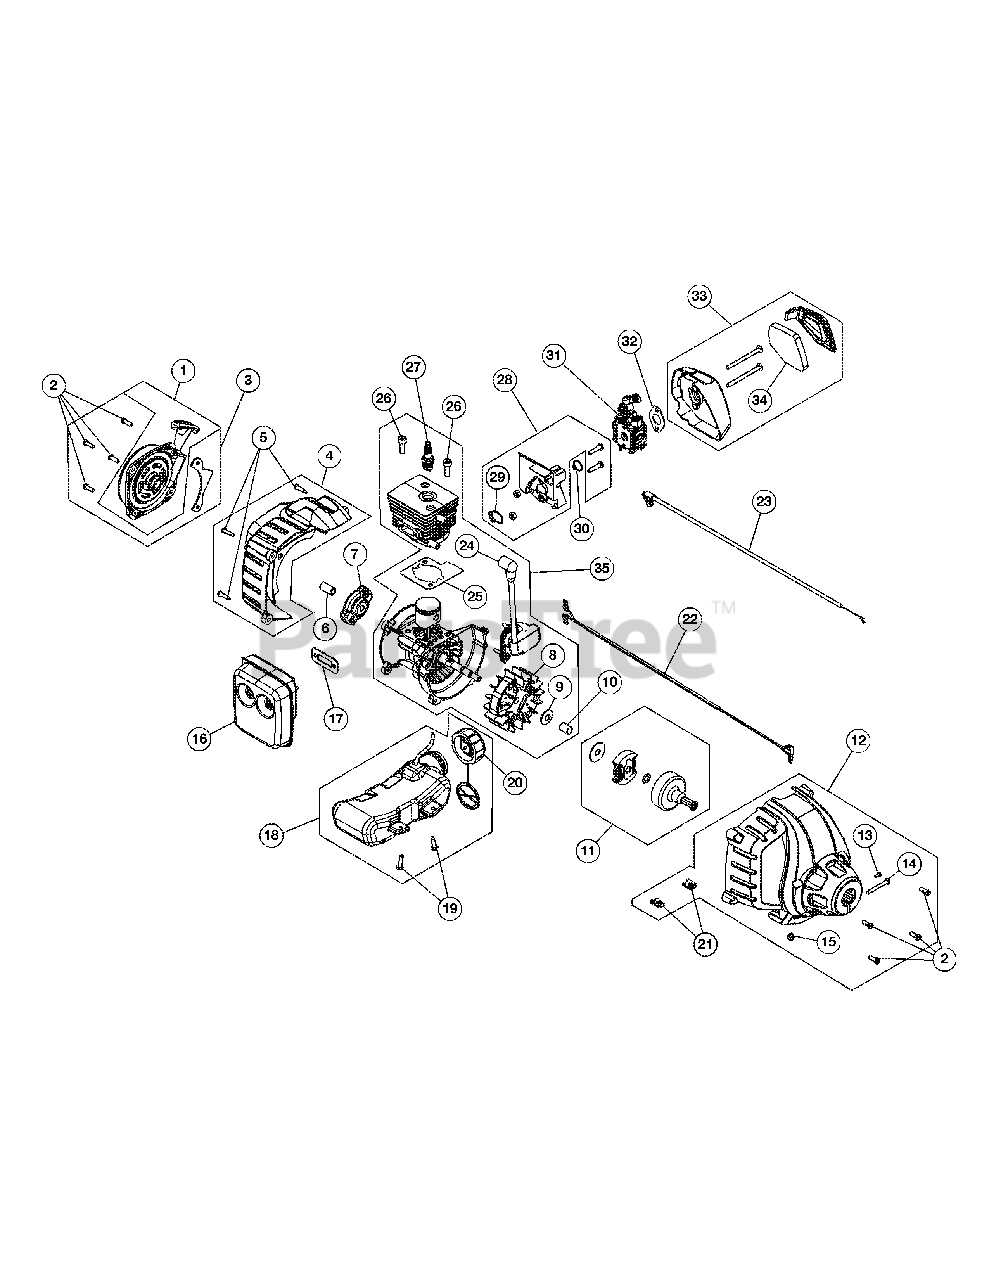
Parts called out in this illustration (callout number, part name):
1	Rear Cover Assembly (Incl. Ref No. 2 & 3)
2	Starter Screw
3	Starter Assembly Guard (Incl. Ref No. 2)
4	Rear Engine Cover (Incl. Ref No. 5)
5	Cover Screw
6	Adapter
7	Pawl Assembly
8	Flywheel Assembly
9	Washer
10	Spacer
11	Clutch Assembly
12	Clutch Cover Assembly (Incl. Ref No. 2, 13-15 & 21)
13	Anti-Rotation Screw
14	Clamp Screw
15	Clamp Nut
16	Muffler Assembly
17	Muffler Gasket
18	Fuel Tank Assembly (Incl. Ref No. 19 & 20)
19	Tank Screw
20	Fuel Cap
21	U-Shaped Nut
22	Lead Wires
23	Throttle Cable
24	Module Assembly
25	Cylinder Gasket
26	Cylinder Bolt
27	Spark Plug
28	Insulator Assembly (Incl. Ref No. 29)
29	Insulator O-Ring
30	Carburetor O-Ring
31	Carburetor
32	Carburetor Gasket
33	Aircleaner Assembly (Incl. Ref No. 34)
34	Aircleaner Filter
35	Short Block Assembly
